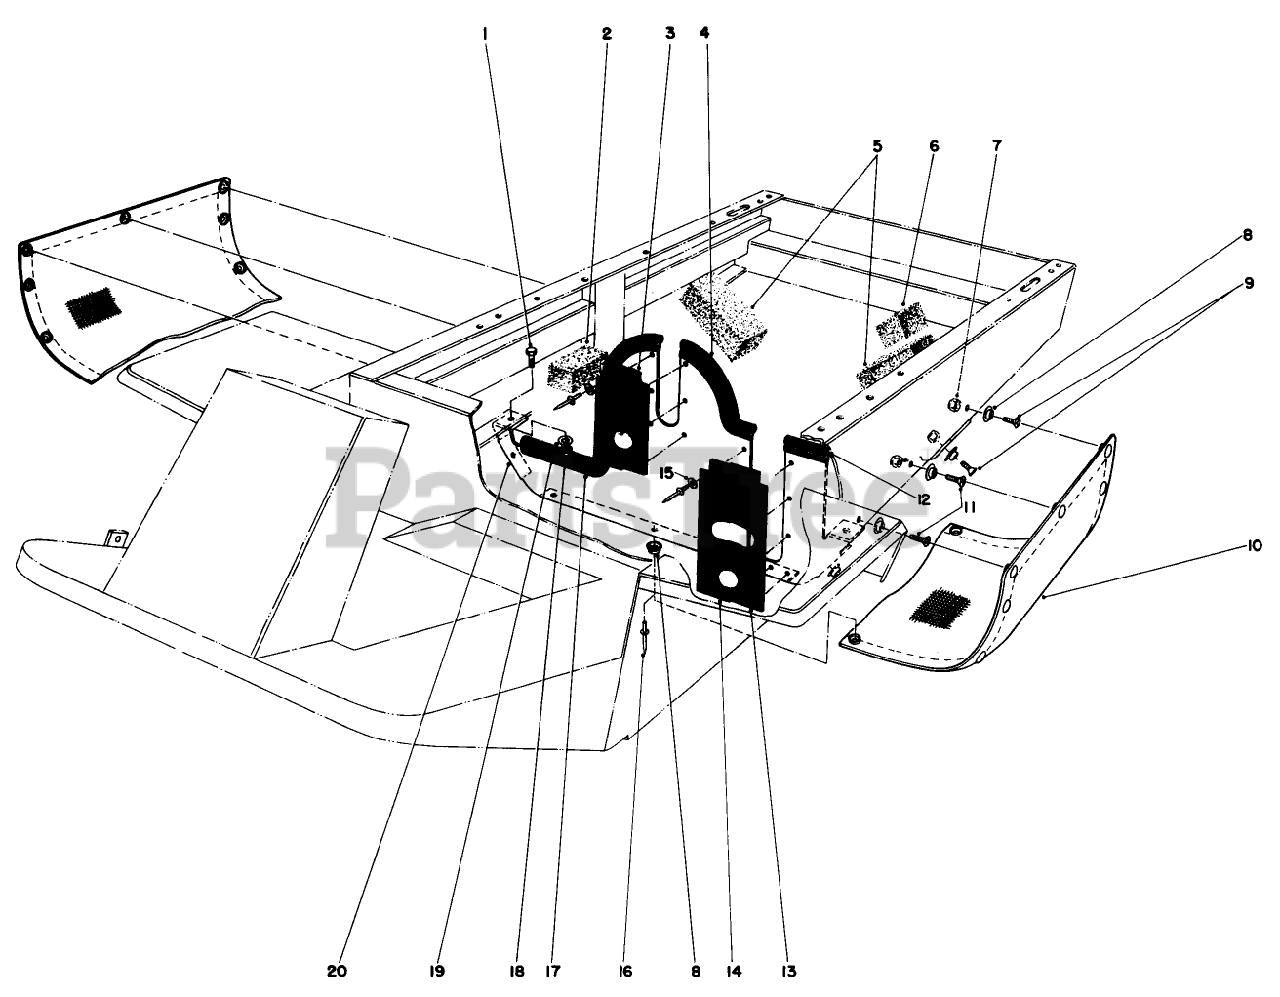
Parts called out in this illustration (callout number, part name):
1	SCREW-HH
7	NUT-HEX
15	WASHER
16	RIVET-POP
18	NUT-HEX
19	WASHER-LOCK/SP
